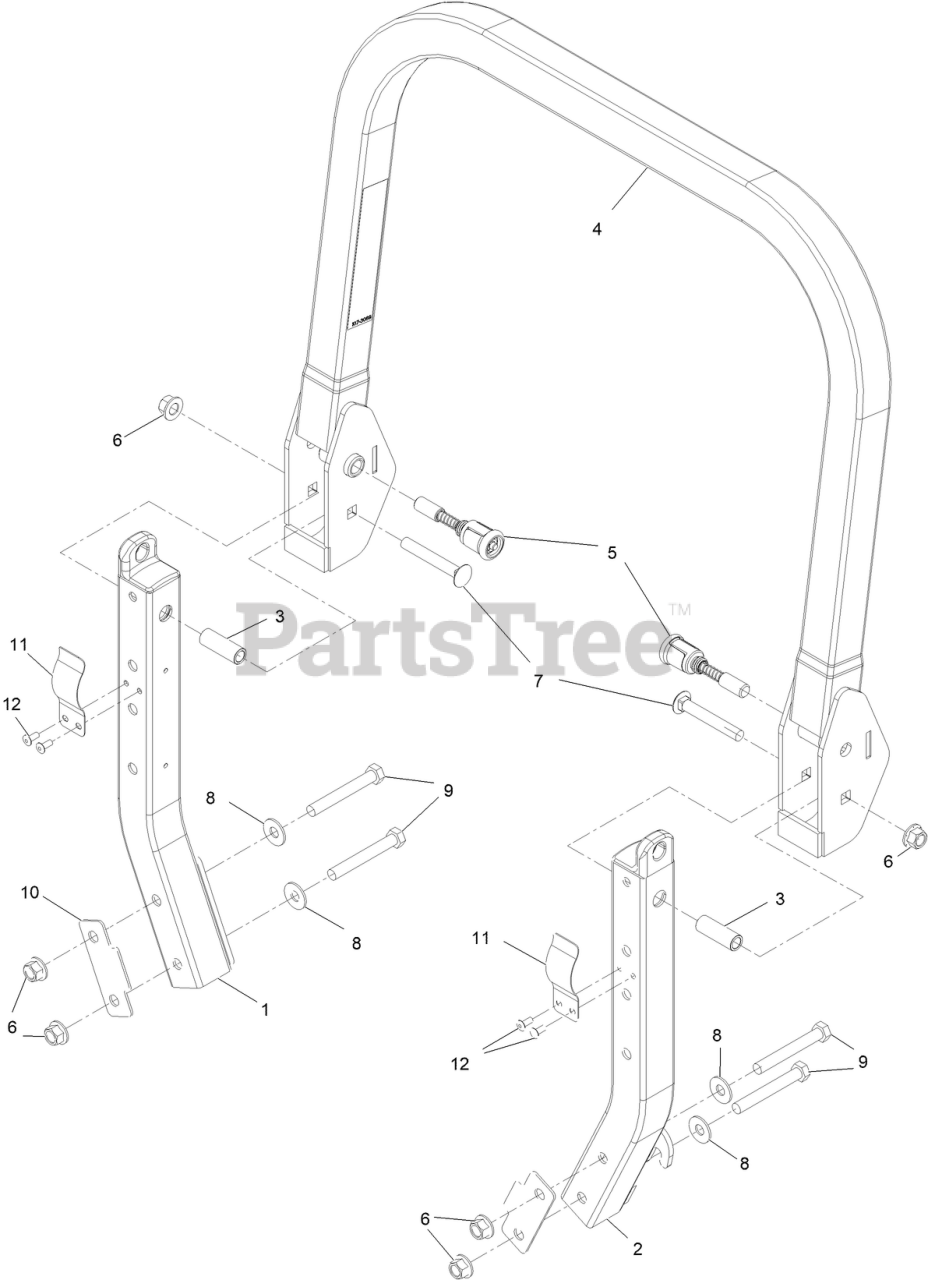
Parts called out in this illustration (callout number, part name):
1	LOWER-ROPS, RH
2	LOWER-ROPS, LH
3	SPACER
4	ASM,ROPS UPPER W/DECAL
5	PIN-SPRING
6	NUT-LOCK
7	SCREW-CARR
8	WASHER-SPRING
9	SCREW-HH
10	SPACER
11	SPRING-LEAF
12	RIVET-BLIND
